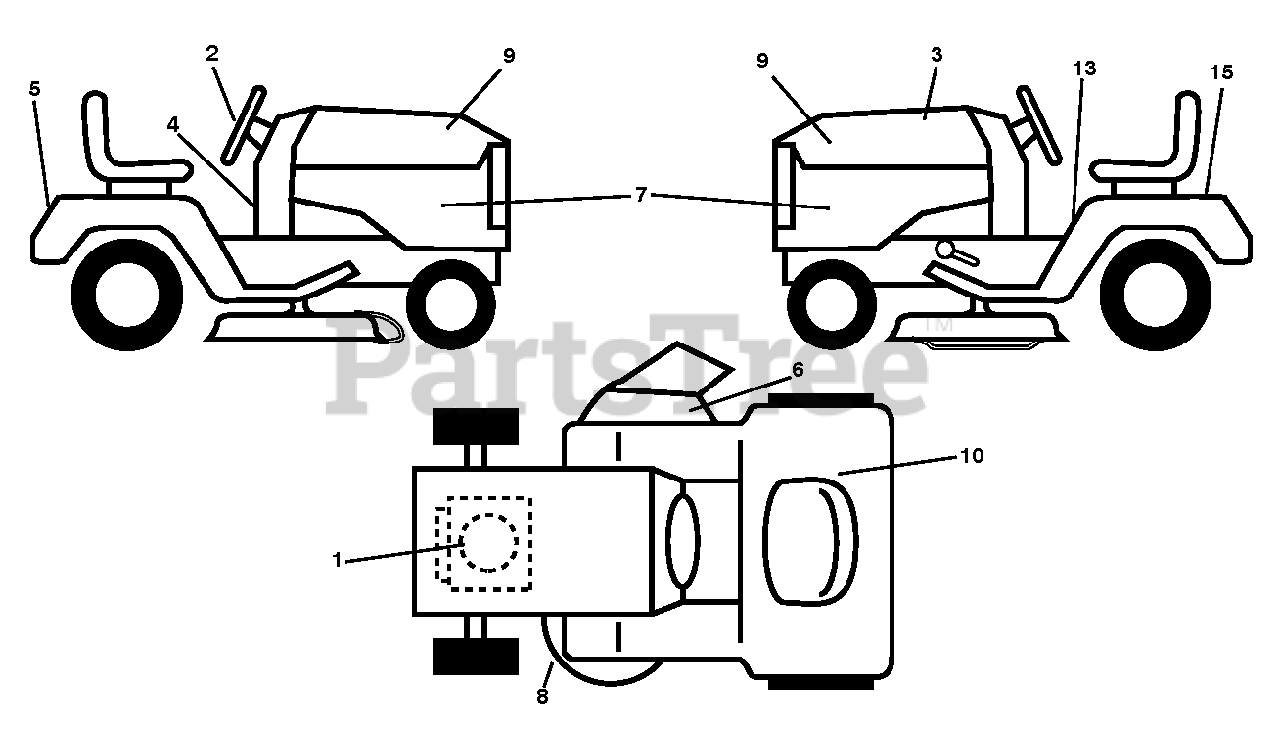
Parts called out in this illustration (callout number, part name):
1	DECAL.ENG.BS.5HP.PB.278978
6	DECAL.WARN.KEEP.HAND.AWAY
8	DECAL V BELT SCHEMATIC
10	DECAL SERVICE
13	Fender Engine Warning Decal
15	DECAL BTRY SYMBOLS
